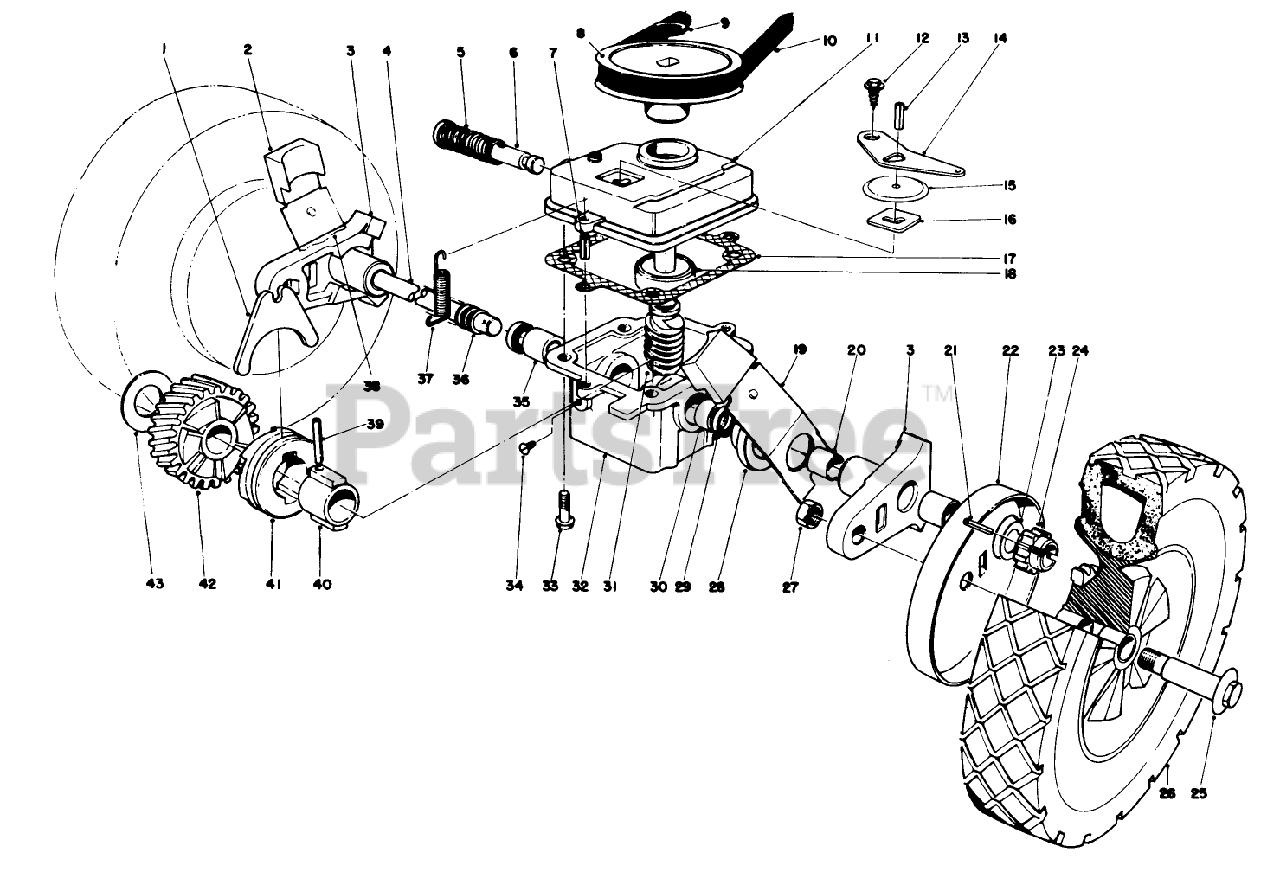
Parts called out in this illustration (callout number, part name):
1	SHIFTER FORK
2	KNOB-ARM
5	SPRING
7	3/16 X 1/2 ROLL PIN
9	PUSH-ON 93-3236
10	BELT-V
13	PIN-ROLL
14	SHIFTER ARM
15	TRANS DUST COVER
16	LATCH PLATE
17	GASKET
20	BUSHING
21	PIN-GROOVED
22	WHEEL COVER
23	WASHER-THRUST
25	BOLT-WHEEL
28	End Cap
30	Bushing
32	GEAR CASE ASM
34	NYLON SCREW
36	COVER-SHAFT, DRIVE
37	TENSION SPRING
38	SPRING ARM ASM SP RH
39	COIL PIN
40	SLEEVE
41	CLUTCH JAW
42	Helical Gear
43	THRUST WASHER
